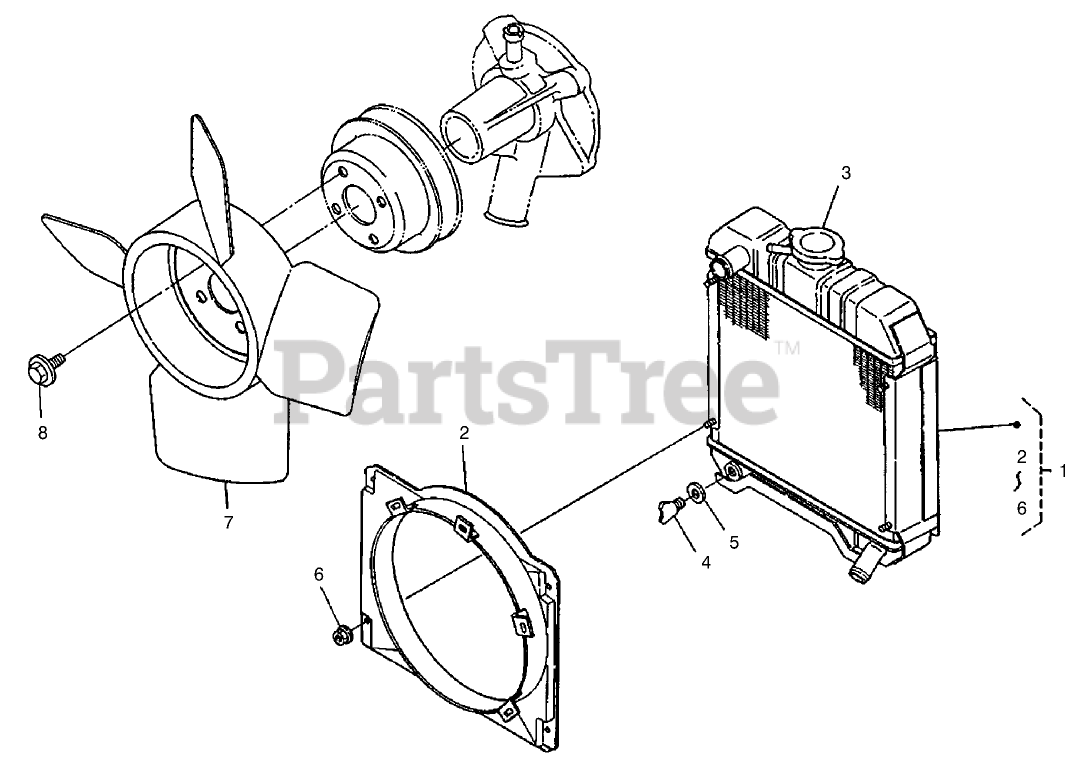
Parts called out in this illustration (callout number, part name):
1	ASSY RADIATOR
2	SHROUD, FAN
3	ASSY CAP
4	COCK, DRAIN
5	GASKET
7	PUSHER FAN
8	BOLT-FLANGE
